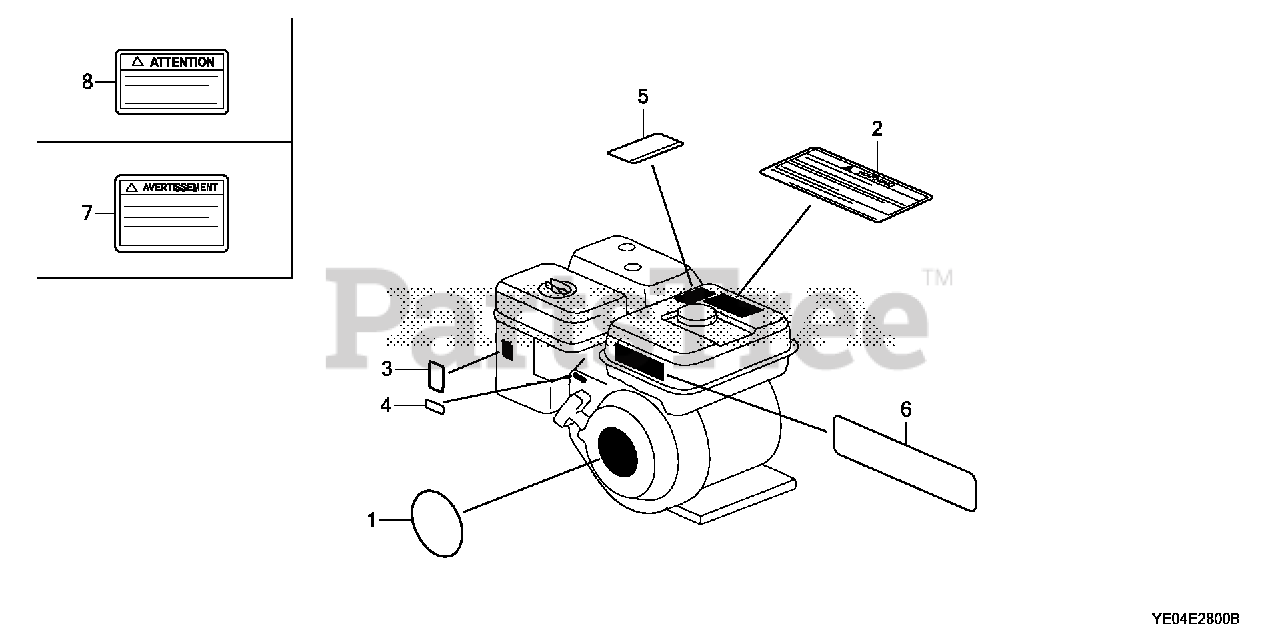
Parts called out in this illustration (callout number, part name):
1	EMBLEM (GX160)
2	LABEL, OPERATOR WARNING (ENGLISH)
3	MARK, CHOKE
5	MARK, EX. CAUTION (ENGLISH)
